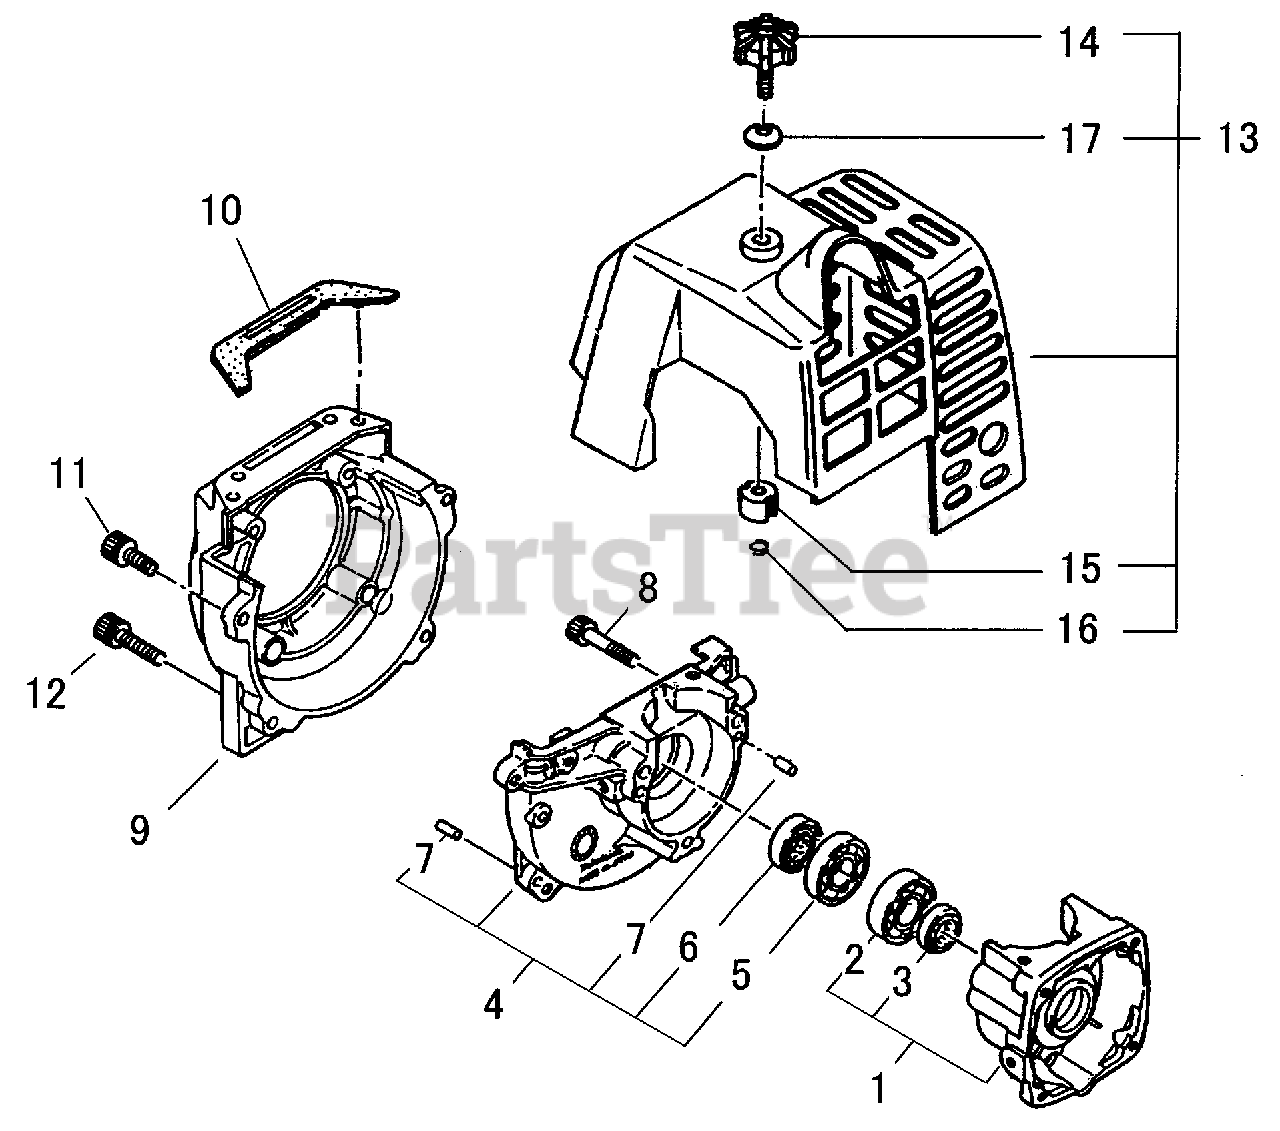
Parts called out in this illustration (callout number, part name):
1	CRANKCASE ASSY, S
2	BEARING, BALL 6001 C3
3	SEAL, OIL 12
4	CRANKCASE ASSY, M
5	BEARING, BALL 6001 C3
6	SEAL, OIL 12
7	PIN, LOCATING Ø4×8
8	BOLT 5×25
9	COVER, FAN
10	CUSHION
11	BOLT M5×16
12	BOLT M5×35
13	COVER KIT, ENGINE
14	THUMBSCREW
15	INSULATOR 5 MM
16	CLIP
17	WASHER, CONE M6
